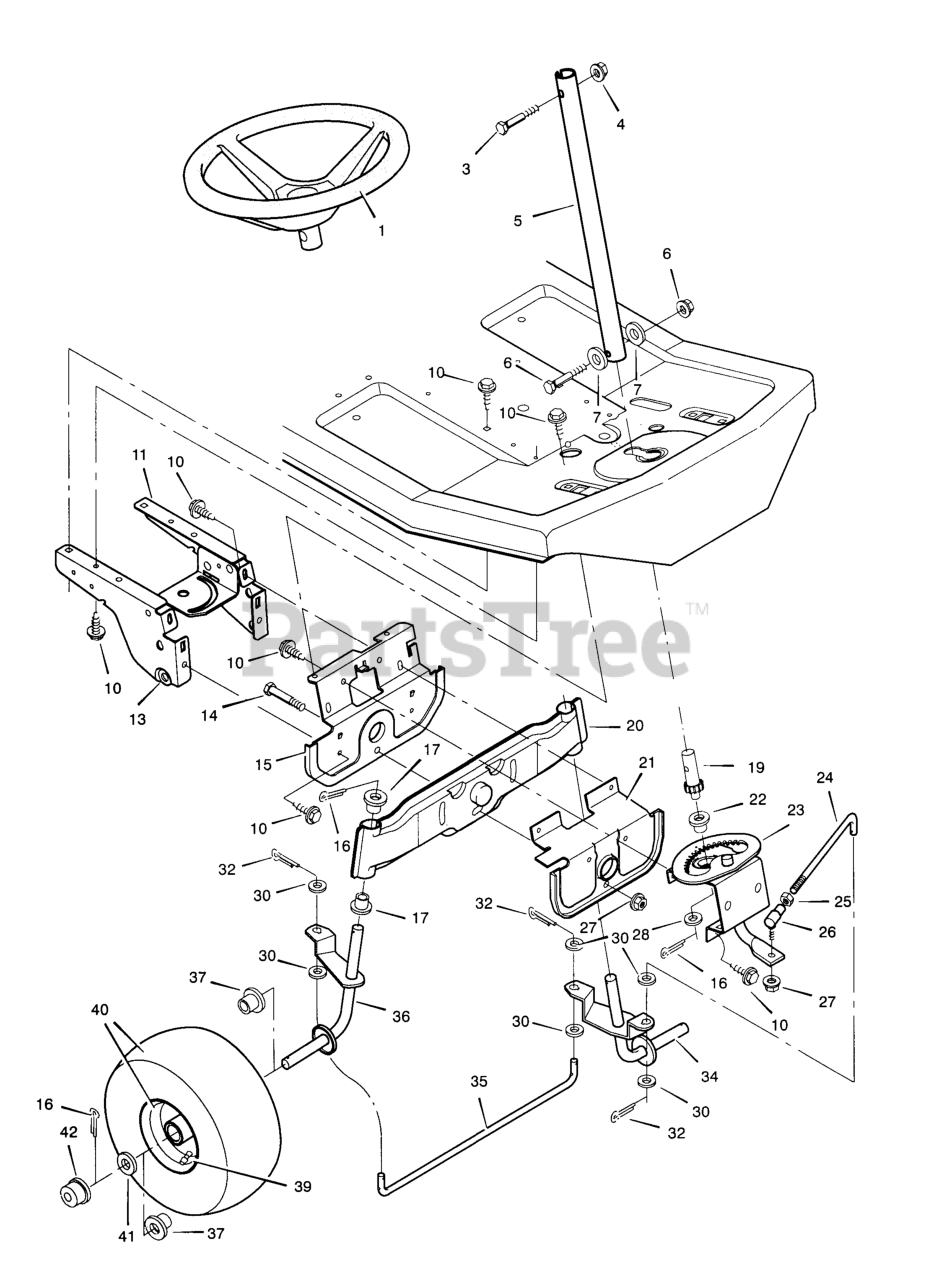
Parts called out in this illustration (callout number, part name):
1	Steering Wheel
3	Bolt, Hex
4	Locknut, Flange
5	Post, Steering
6	Nut, Hex
7	Washer
11	Plate, Left Suspension
13	Plate, Right Suspension
14	Bolt, Hex
15	Support, Front Axle
16	Pin, Cotter
17	Bearing, Spindle
19	Gear, Pinion
20	Axle Assembly, Front
21	Hanger Assembly, Front Axle
22	Bearing
23	Sector Assembly
24	Rod, Drag Link
25	Ball Joint, Steering
26	Nut, Hex
27	Locknut, Flange
28	Washer
30	Washer
32	Pin, Cotter
34	Spindle Assembly, Left
35	Rod, Tie
36	Spindle Assembly, Right
37	Bearing, Wheel
39	Valve Stem
40	Wheel & Tire Assembly
42	Cap, Hub
